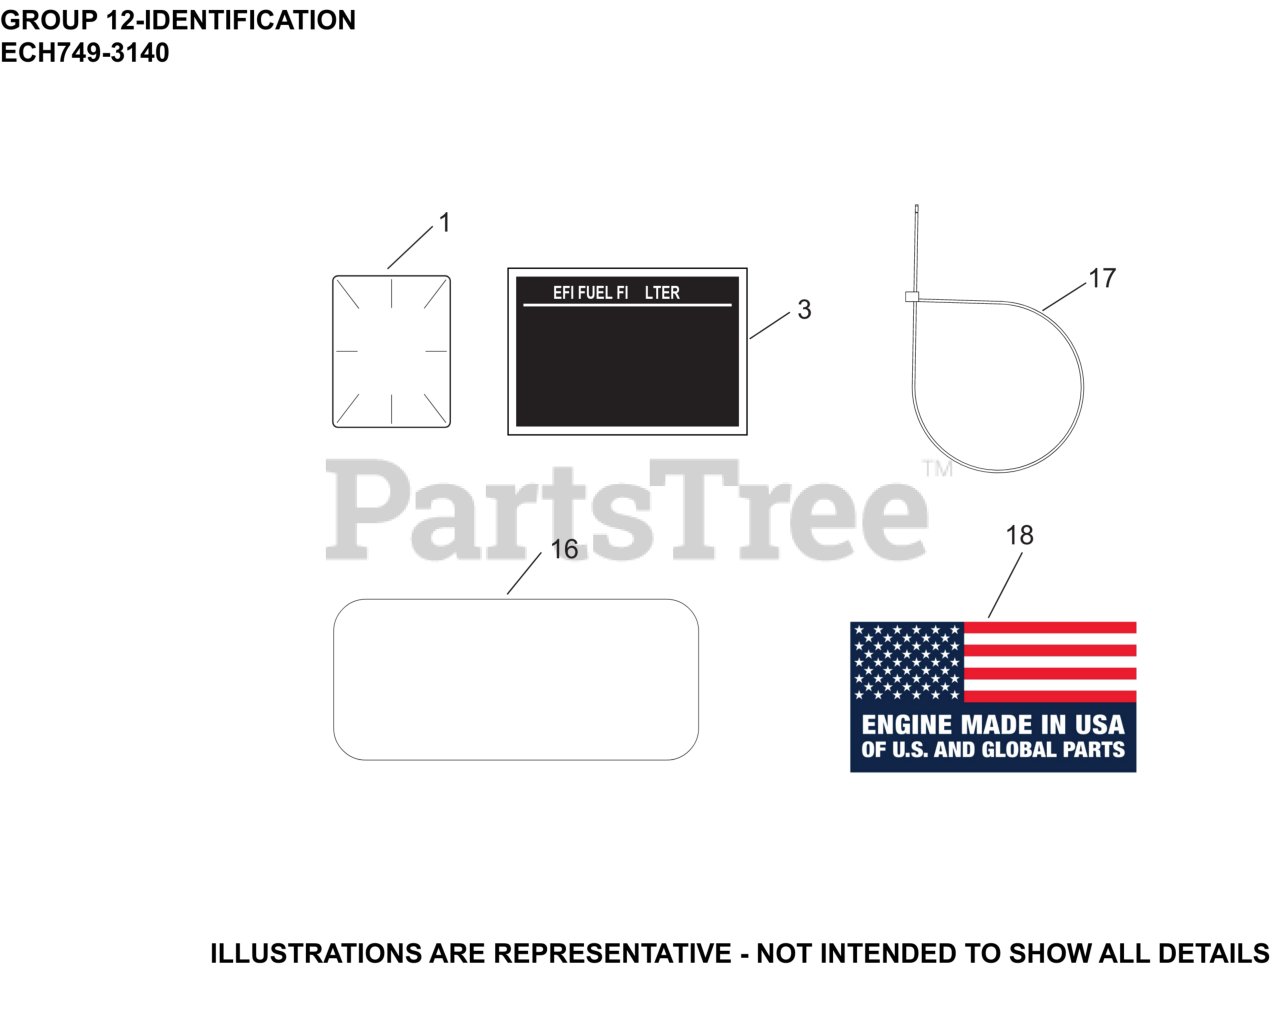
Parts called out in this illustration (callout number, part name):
1	LABEL, CLEAR LAMINATION
3	LABEL, EFI FUEL FILTER
16	LABEL, CANADIAN COMPLIANCE
18	DECAL, USA
